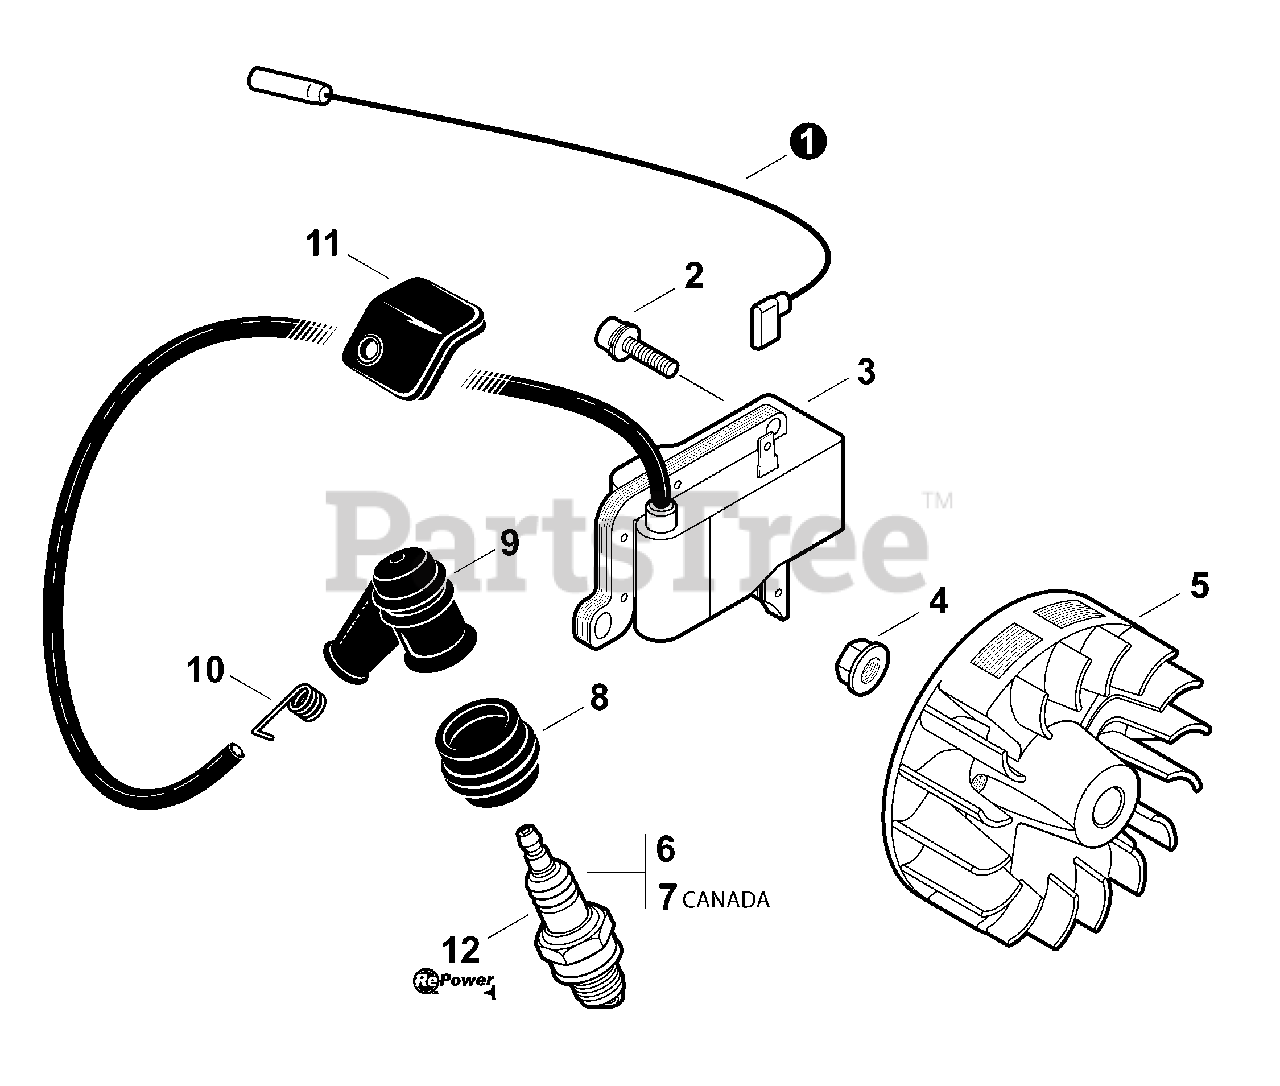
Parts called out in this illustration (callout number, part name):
1	LEAD - IGNITION 145 MM
2	BOLT 5×16
3	COIL, IGNITION
4	NUT, FLANGE M8
5	FLYWHEEL
6	SPARK PLUG - BPM8Y
7	SPARK PLUG - BPMR8Y
8	COVER, CAP
9	CAP, SPARK PLUG
10	TERMINAL, SPARK PLUG
12	TUNE-UP KIT - REPOWER
